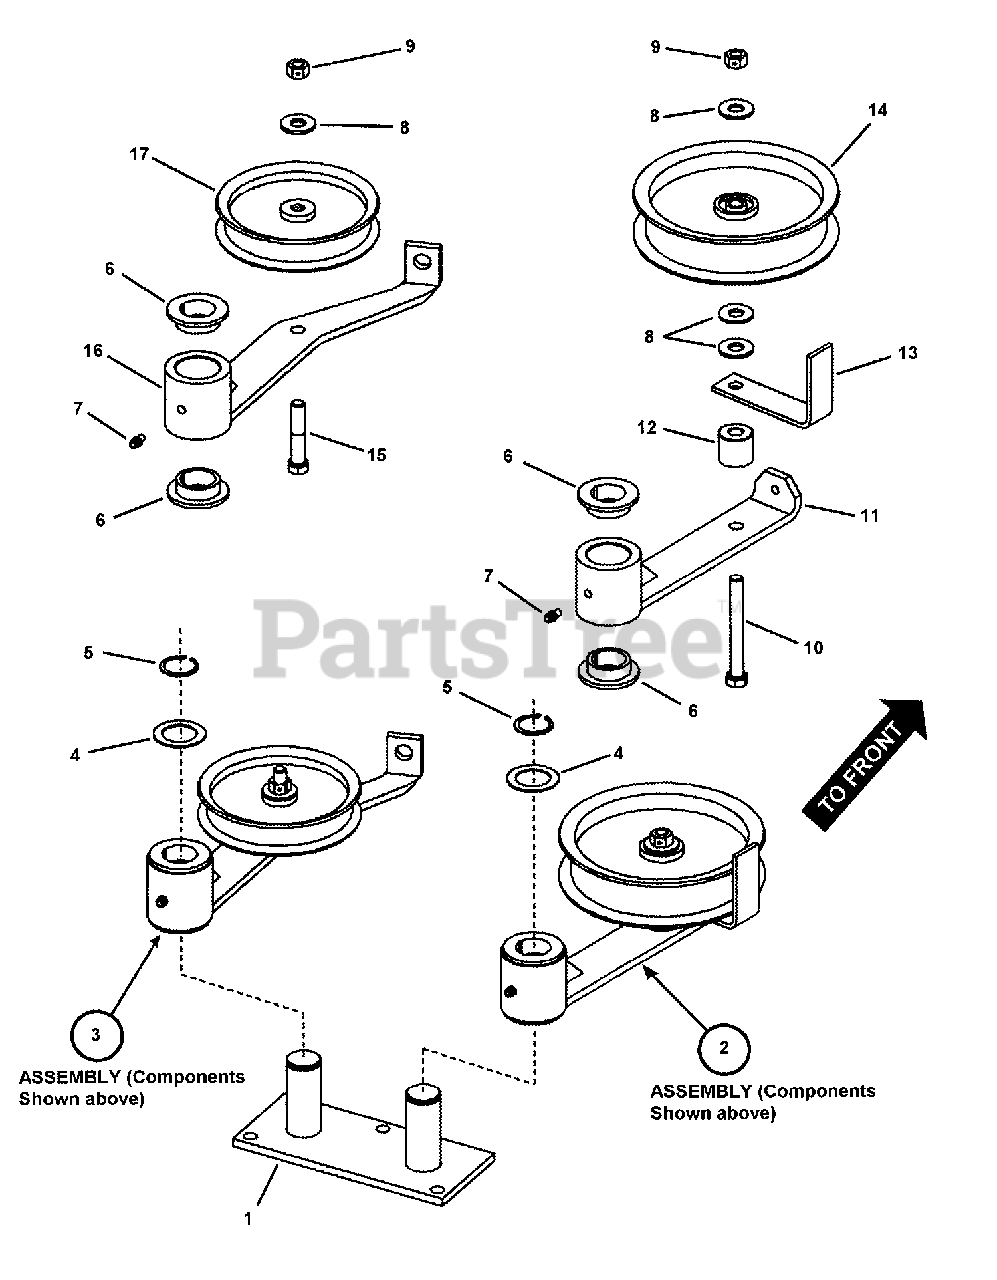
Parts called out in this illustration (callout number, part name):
1	WELDMENT, Idler Plate
2	ASSEMBLY, Primary Idler
3	ASSEMBLY, Secondary Idler
4	BUSHING, 1" Machine
5	RING, 1" External Retaining
6	BUSHING, Idler (Powdered Metal)
7	LUBE FITTING, 3/16"
8	WASHER, 3/8" USS
9	NUT, 3/8-16 Hex Center Lock, GR 5 or B
10	SCREW, 3/8-16 x 3-1/4" Hex Head Cap, GR 5
11	WELDMENT, Primary Idler Arm
12	BUSHING - Idler
13	RETAINER, Idler Belt
14	PULLEY, Flat Idler
15	SCREW, 3/8-16 x 1-3/4" Hex Head Cap, GR 5
16	WELDMENT, Secondary Idler Arm
17	PULLEY, Idler
